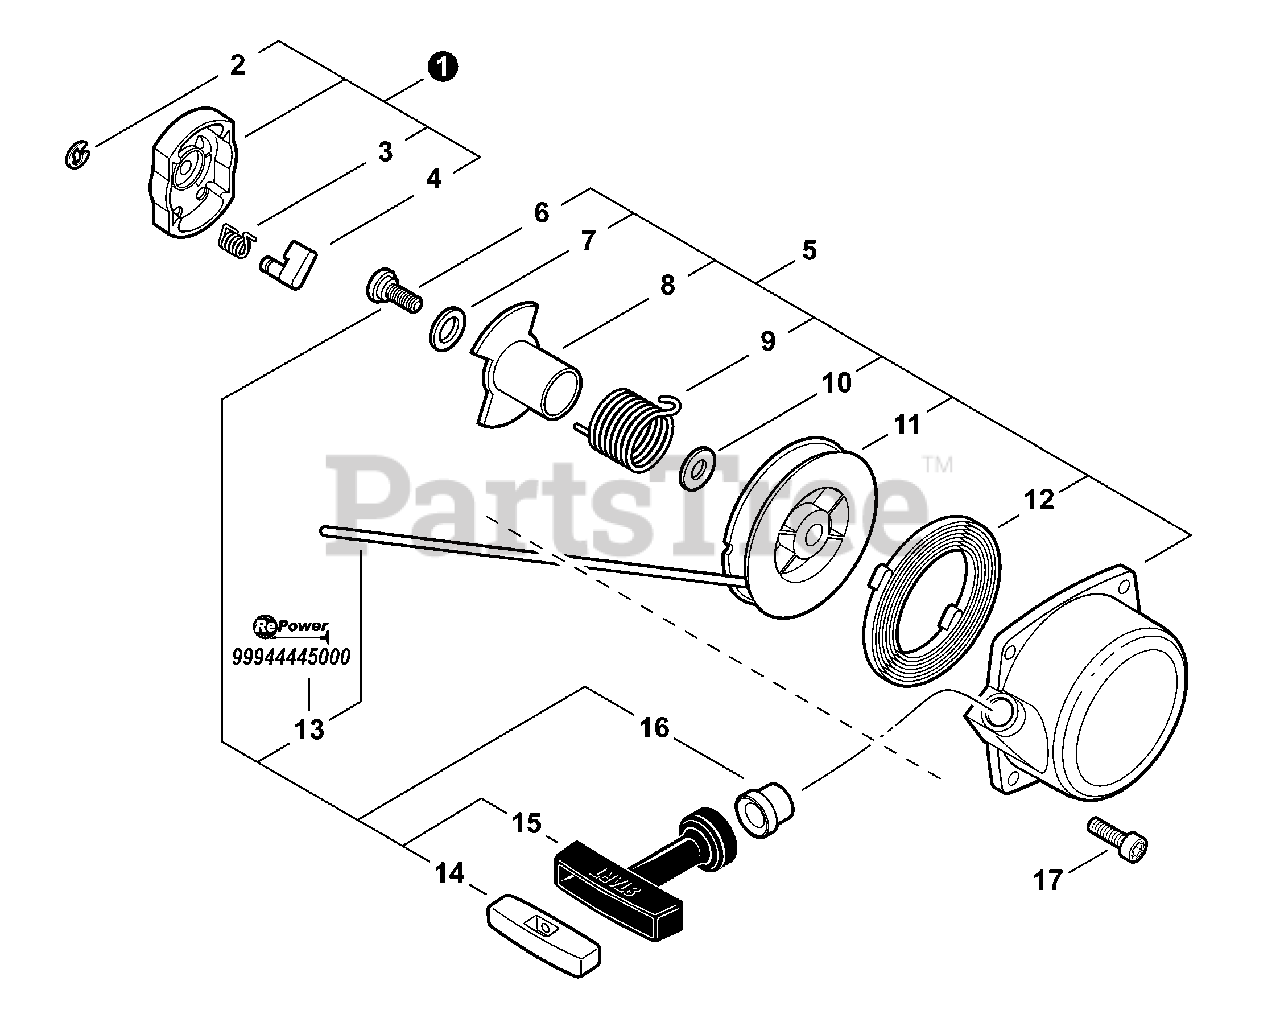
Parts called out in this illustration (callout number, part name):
1	STARTER PAWL ASSY
2	RING, RETAINING - 4
3	SPRING, RETURN
4	PAWL, STARTER
5	STARTER ASSY
6	SCREW
7	WASHER, THRUST
8	CATCHER, PAWL
11	REEL, ROPE
12	SPRING, REWIND
13	ROPE, STARTER - 3.5×1000
14	RETAINER, ROPE
15	GRIP, STARTER
16	GUIDE, ROPE
17	SCREW - 5×16
